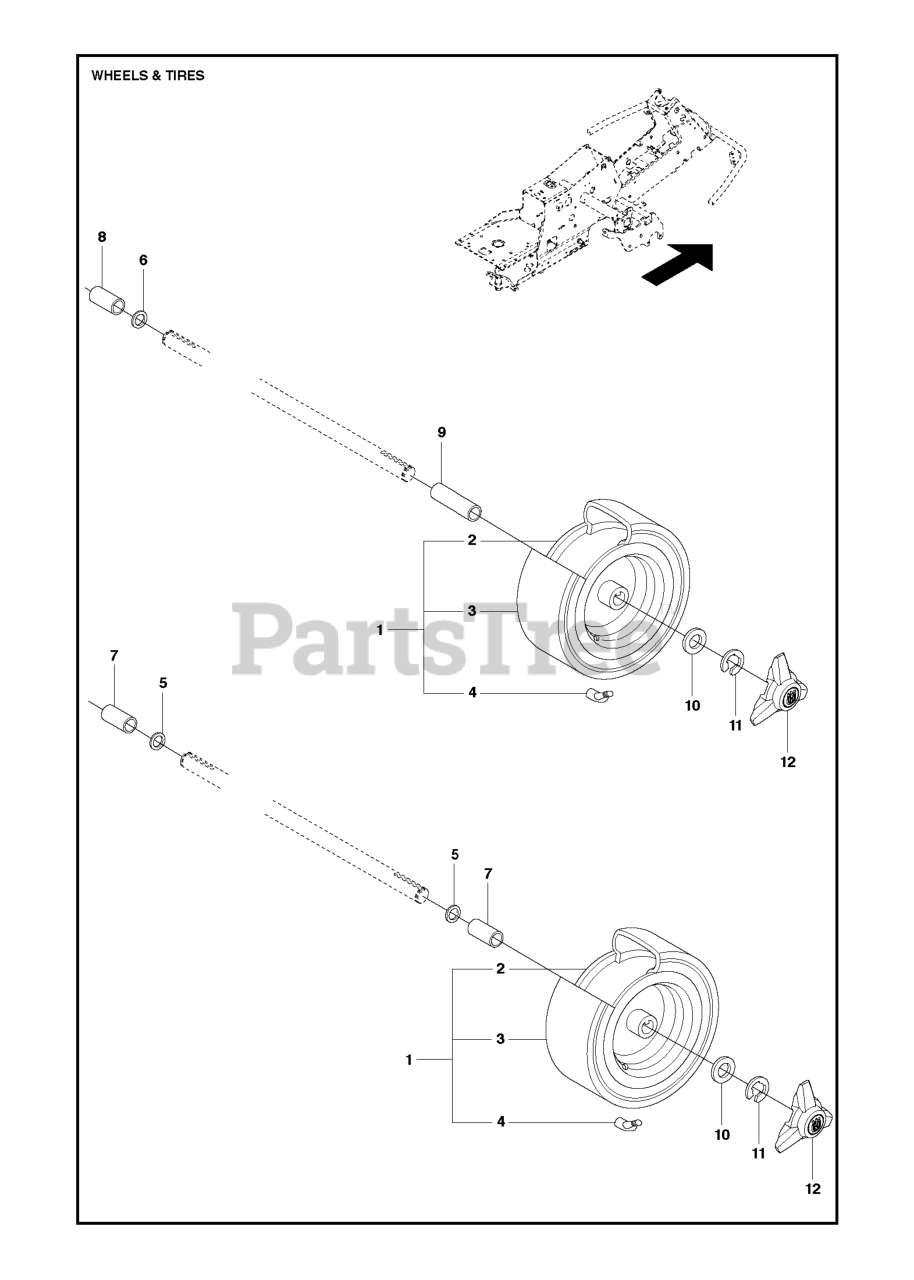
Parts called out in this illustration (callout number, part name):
3	TIRE
4	VALVE
7	SPACE SLEEVE
11	RETAINING RING
